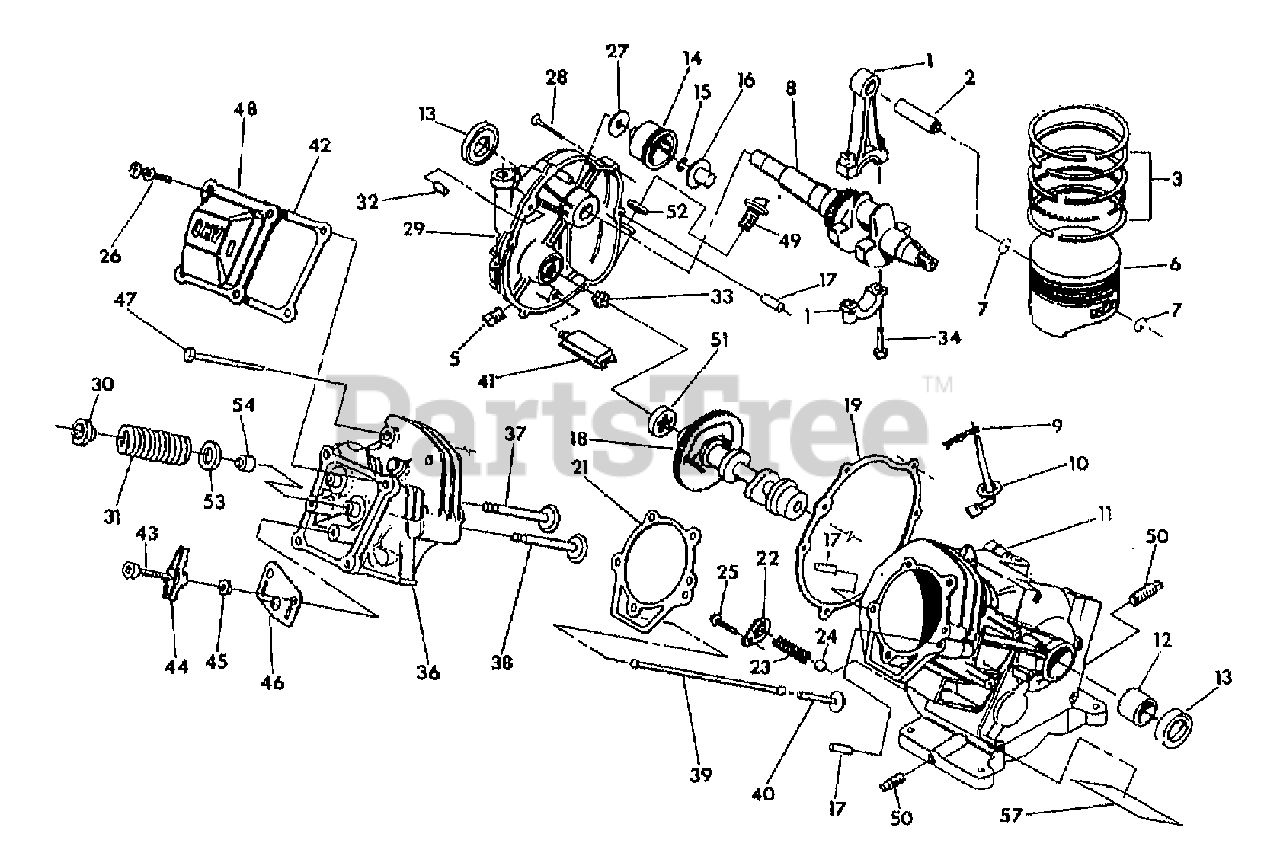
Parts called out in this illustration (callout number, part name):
1	ROD-CONNECTING W/CAP
2	PIN-PISTON
3	RING-(SET)PISTON (PRS WSHR)
5	PLUG-1/8" NPTF PIPE
7	RETAINER-PISTON PIN
8	ASSM-CRANKSHAFT
9	PIN-"R" GOVERNOR ARM
10	ARM-GOVERNOR
11	SUB ASSM-CRANKCASE
12	BEARING-SLEEVE
13	SEAL-CRANKSHAFT
14	ASSM-GEAR GOVERNOR
15	RETAINER-GOVERNOR ("C" RING)
16	SPOOL-GOVERNOR
17	DOWEL-12"DIA. SLEEVE
18	ASSM-CAMSHAFT
19	GASKET-CRANKCASE
21	GASKET-CYLINDER HEAD
22	RETAINER-SPRING OIL PRESS.
23	SPRING-OIL PRESSURE
24	BALL-PRESSURE RELIEF
25	SCR M5-0.8X8MM (THD FORMING)
26	SCR M6-1.0X12MM
27	WASHER-THRUST
28	SCR-HFLK
29	SUBASSM-GEAR COVER
30	RETAINER-VALVE SPRING
31	SPRING-VALVE
32	PIN-DOWEL M12X20
33	GEROTOR-INNER
34	BOLT-CONNECTING ROD
36	CYL HEAD W/VALVE SEATS & GUIDE
37	VALVE-EXHAUST
38	VALVE-INTAKE
39	ROD-PUSH GEN #88396A
41	ASSM-OIL PICKUP
42	GASKET-ROCKER COVER
43	STUD-PIVOT BALL
44	ARM-ROCKER
45	NUT-HEX/JAM (ROCKER ARM)
46	PLATE-PUSH ROD GUIDE
47	SCR-M8X50MM HEAD
48	ASSM-ROCKER CVR BREATHER
49	PLUG-OIL FILL
50	PLUG-1/4" NPT PIPE
51	GEROTOR-OUTER 6/5
52	RING-O 17.8MM IDX2.4MM
53	WASHER-VALVE SPRING
54	SEAL-VALVE STEM
57	DECAL-SER/NO. PRESS/WASHR
